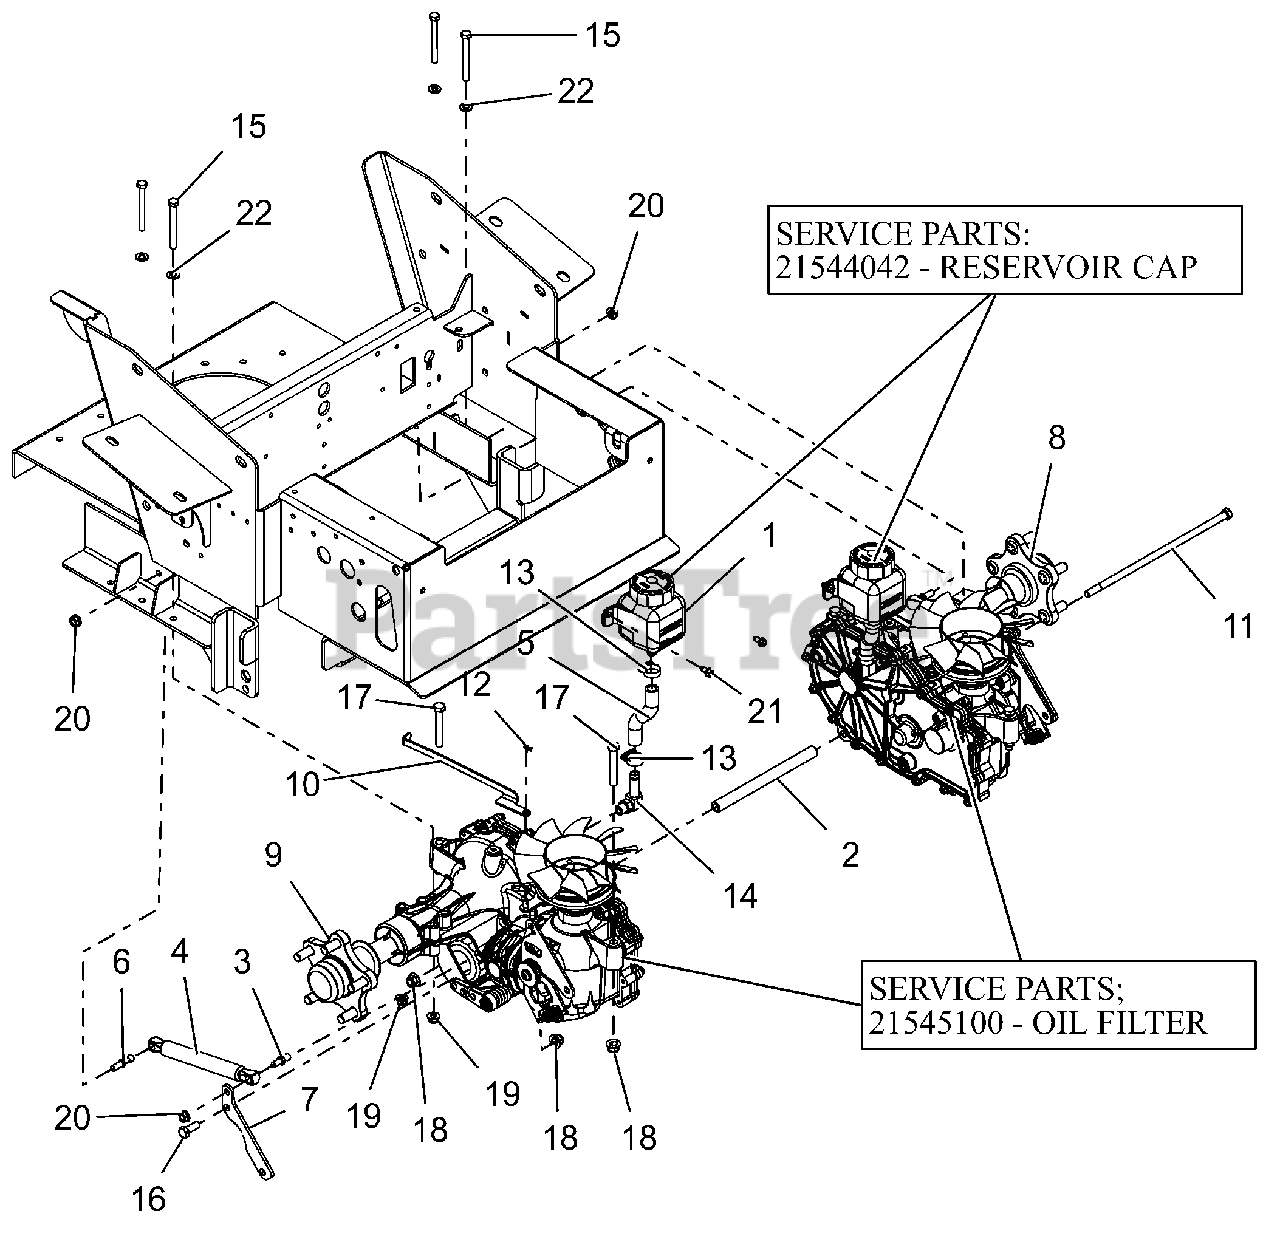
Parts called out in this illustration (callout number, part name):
1	TANK, EXPANSION
1	CAP, HYDRO RESERVOIR REPLAC.
2	SPCR,.406 ID X .630 OD X 7.724
3	STUD- BALL
4	DAMPER
5	HOSE, 100I HYDRO OVERFLOW
6	STUD-BALL-THREADED
7	TRANSMISSION DAMPER MTG PLT-BL
8	TRANSAXLE, ZT3400 LH
9	TRANSAXLE, ZT3400, RH
9	OIL FILTER, TRANSMISSION
10	DUMP VALVE BRKT - BLACK
11	BLT HEX, .38-16X11.00 GR5 YWZC
12	PIN-HAIR INT .06X.18X.77
13	CLAMP,.88 DIA. HOSE
14	FITTING, HYD (90 DEG)
15	@BLT-HEX .31-18X3.00 GR5 YWZC
16	@BLT-HEX .38-16X1.00 GR5 YWZC
17	@BLT-HEX .38-16X2.50 GR5 YWZC
18	@NUT-LK-NYL-FLG .38-16 YWZC
19	@NUT-LK-NYL-FLG .31-18 YWZC
20	@NUT-LK-TOP-FLG .31-18 YWZC
21	SCR-TAP .25-20X.50 HWH TR YWZ
22	@WSHR-FL-STL.344X.688X.065YWZC
